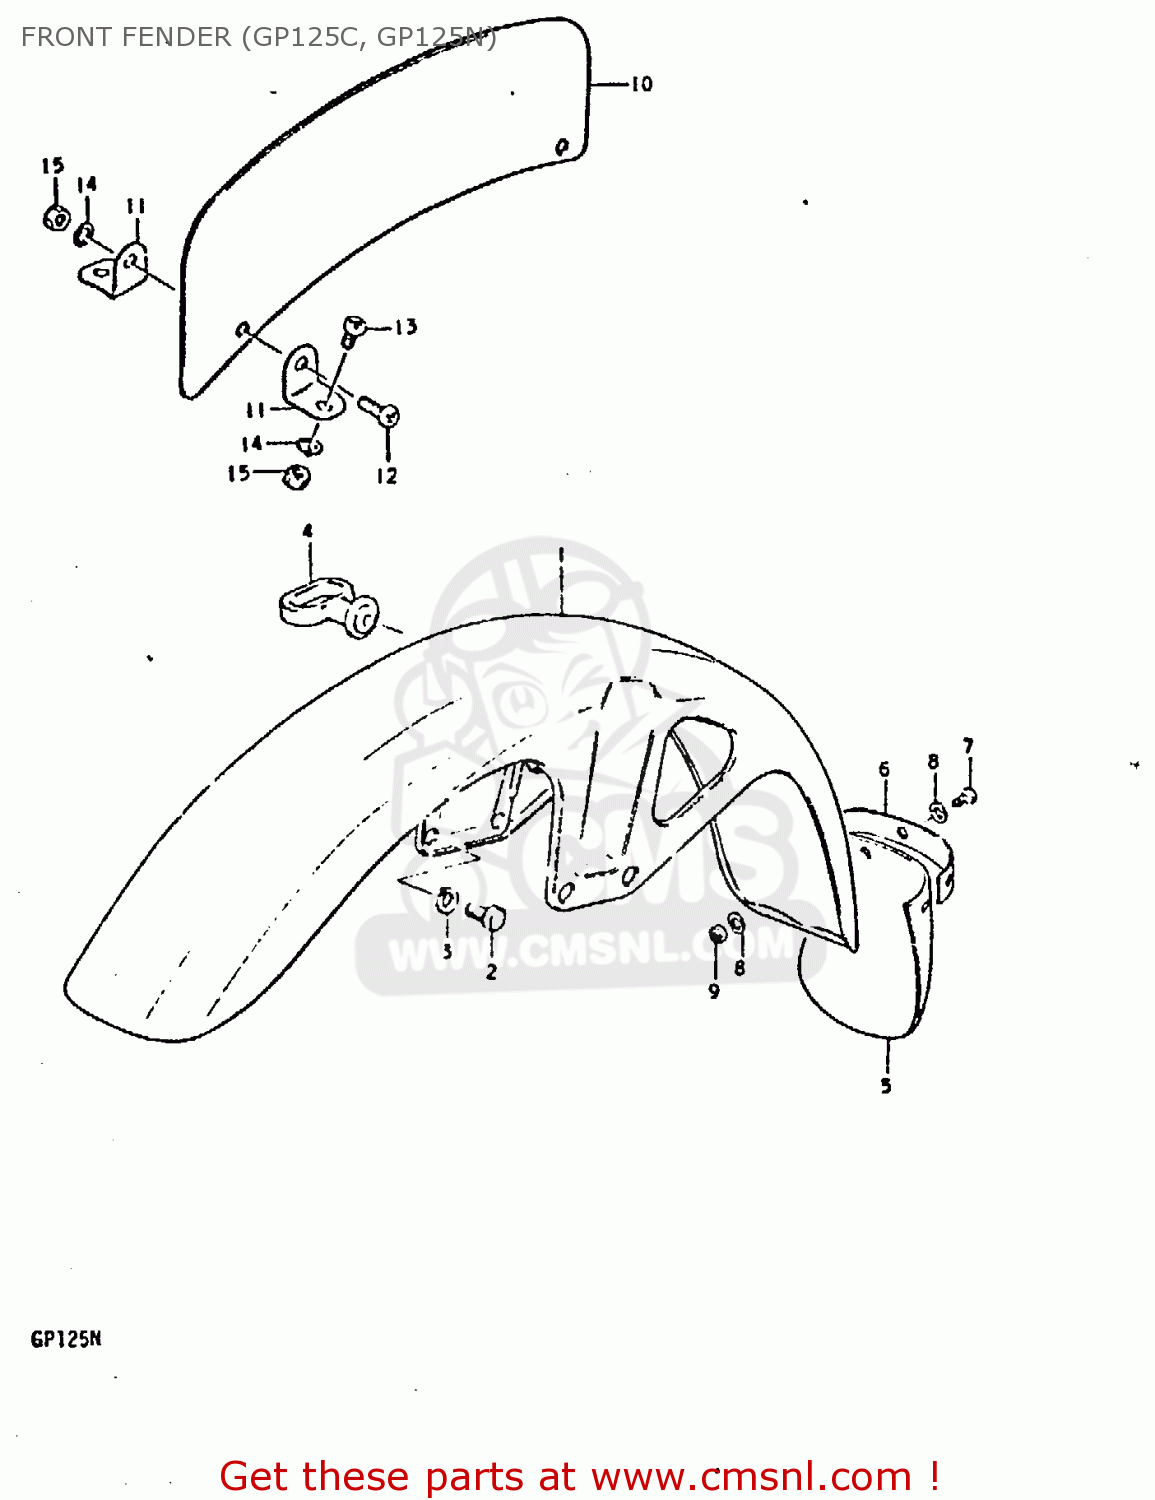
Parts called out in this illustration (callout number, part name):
1	FENDER, FRONT
2	BOLT
3	LOCK WASHER
4	GUIDE,CABLE
5	FLAP,MUD
6	PLATE,MUDFLAP
7	SCREW 4X10
8	WASHER
9	NUT 4MM
